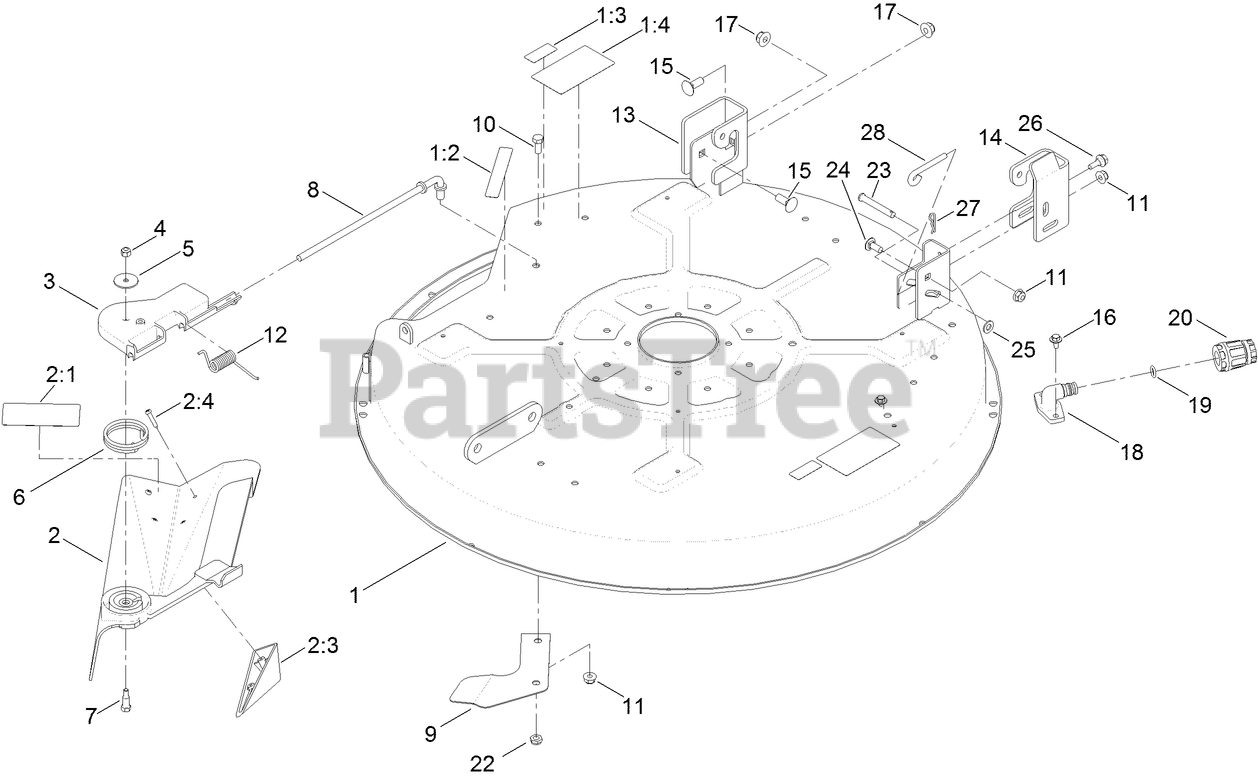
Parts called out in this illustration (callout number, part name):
1	32 INCH DECK AND DECAL ASM
1:2	DECAL-DANGER
1:3	DECAL-DANGER
1:4	DECAL-DANGER
2	32 INCH DEFLECTOR ASM
2:1	DECAL-DANGER
2:3	KICKER
2:4	SCREW-PPH
3	PIVOT-HINGE, DEFLECTOR
4	NUT-LOCK, NI
5	WASHER-FLAT
6	SPRING-TORSION
7	BOLT-SHOULDER
8	ROD-PIVOT
9	RAMP-DEFLECTOR
10	SCREW-HH
11	NUT-HF, NI
12	SPRING-TORSION
13	BRACKET-HANGER, RH
14	BRACKET-HANGER, LH
15	BOLT-CARR
16	SCREW-HHFTF
17	NUT-HF, NI
19	O-RING
20	CONNECTOR-HOSE
23	PIN-CLEVIS
24	SCREW-CARR
25	WASHER-PLAIN
26	SCREW-SHOULDER,HWH
27	PIN-COTTER
28	ROD-LEVEL, DECK
